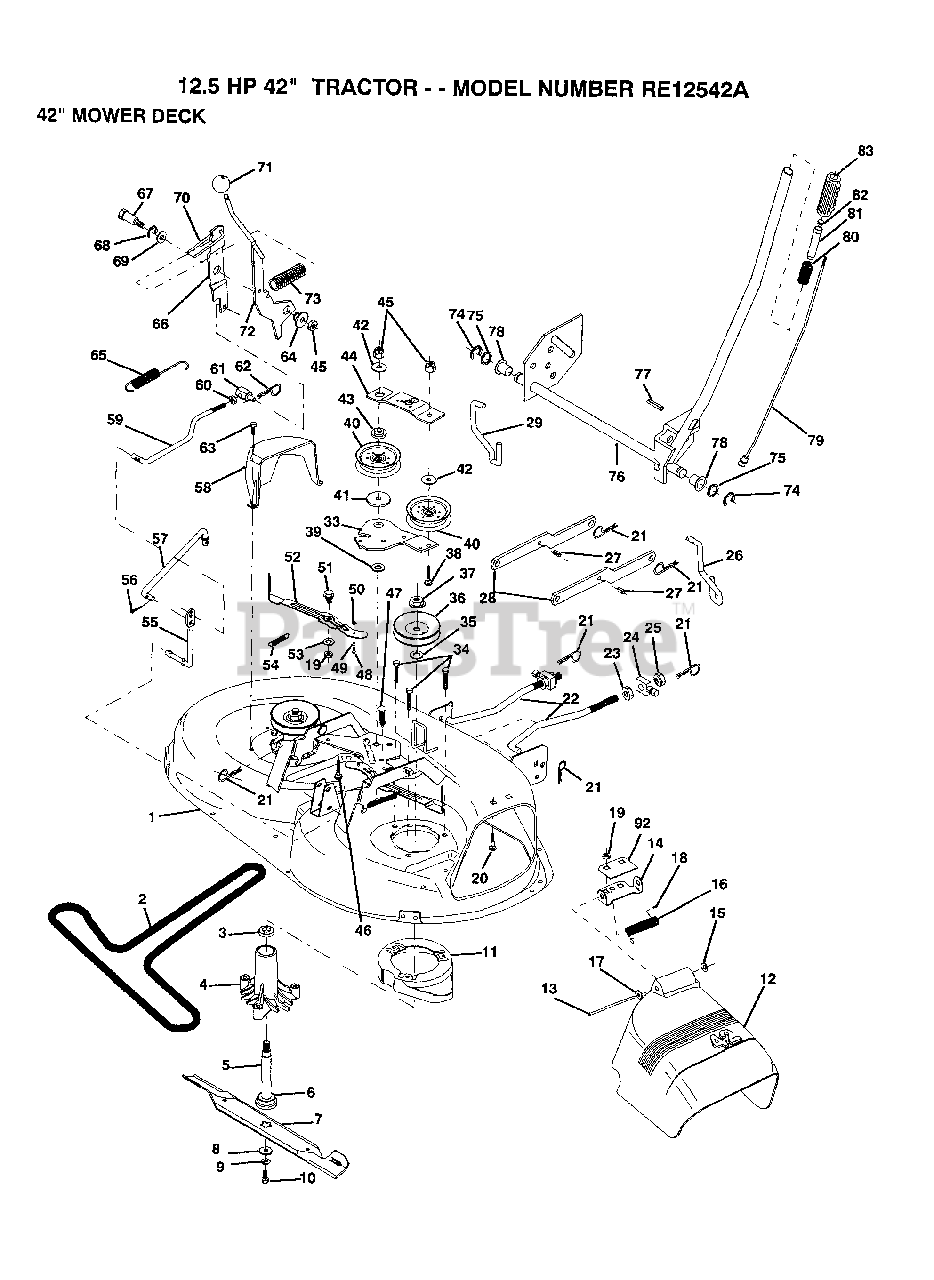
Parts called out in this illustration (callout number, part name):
2	BELT-V.92.4.MWR
3	BEARING
4	HSG ASM MANDREL
6	BEARING.BALL
8	WASHER BLADE
10	BLADE BOLT
12	DEFLECTOR.SHIELD
13	HINGE ROD
14	DEFLECTOR BRKT
15	NUT PUSH M
16	SPRING TORSION
17	WASHER
18	CAP-SLEEVE LT
20	BOLT
22	LINK.FRONT
23	NUT
24	TRUNION
25	NUT.LK.W/WSH.1/2.
26	LIFT LINK RH
27	"PIN,SPRING"
28	SUSP ARM ASM REAR
29	LINK LIFT LH
33	IDLER ARM
35	WASHER
38	BOLT
39	HARDENED WASHER
40	FLAT IDLER PULLEY
41	SPACER RETAINER
42	WASHER GT
43	RETAINER SPACER
44	IDLER ARM STIFF
46	BOLT CARRIAGE
47	XMAS TREE FASTNER
48	SHOULDER BOLT
50	LOCKNUT
52	BRAKE PAD ARM ASM
53	HARD SMALL WASHER
54	SPRING EXTENSION
55	PIVOT ROD
57	CLUTCH ROD SECOND
60	NUT
61	TRUNION
62	RETAINER M
63	SCREW LT
64	BUSHING
65	RETURN SPRING
66	CLUTCH ARM SECOND
67	SHOULDER BOLT
68	RING
69	WASHER
70	SPRING KEEPER
72	CLUTCH ARM PRI AS
75	WASHER
77	PIN-GROOVE LT
78	NYLON BEARING
83	GRIP
92	STIFFENER BRKT
